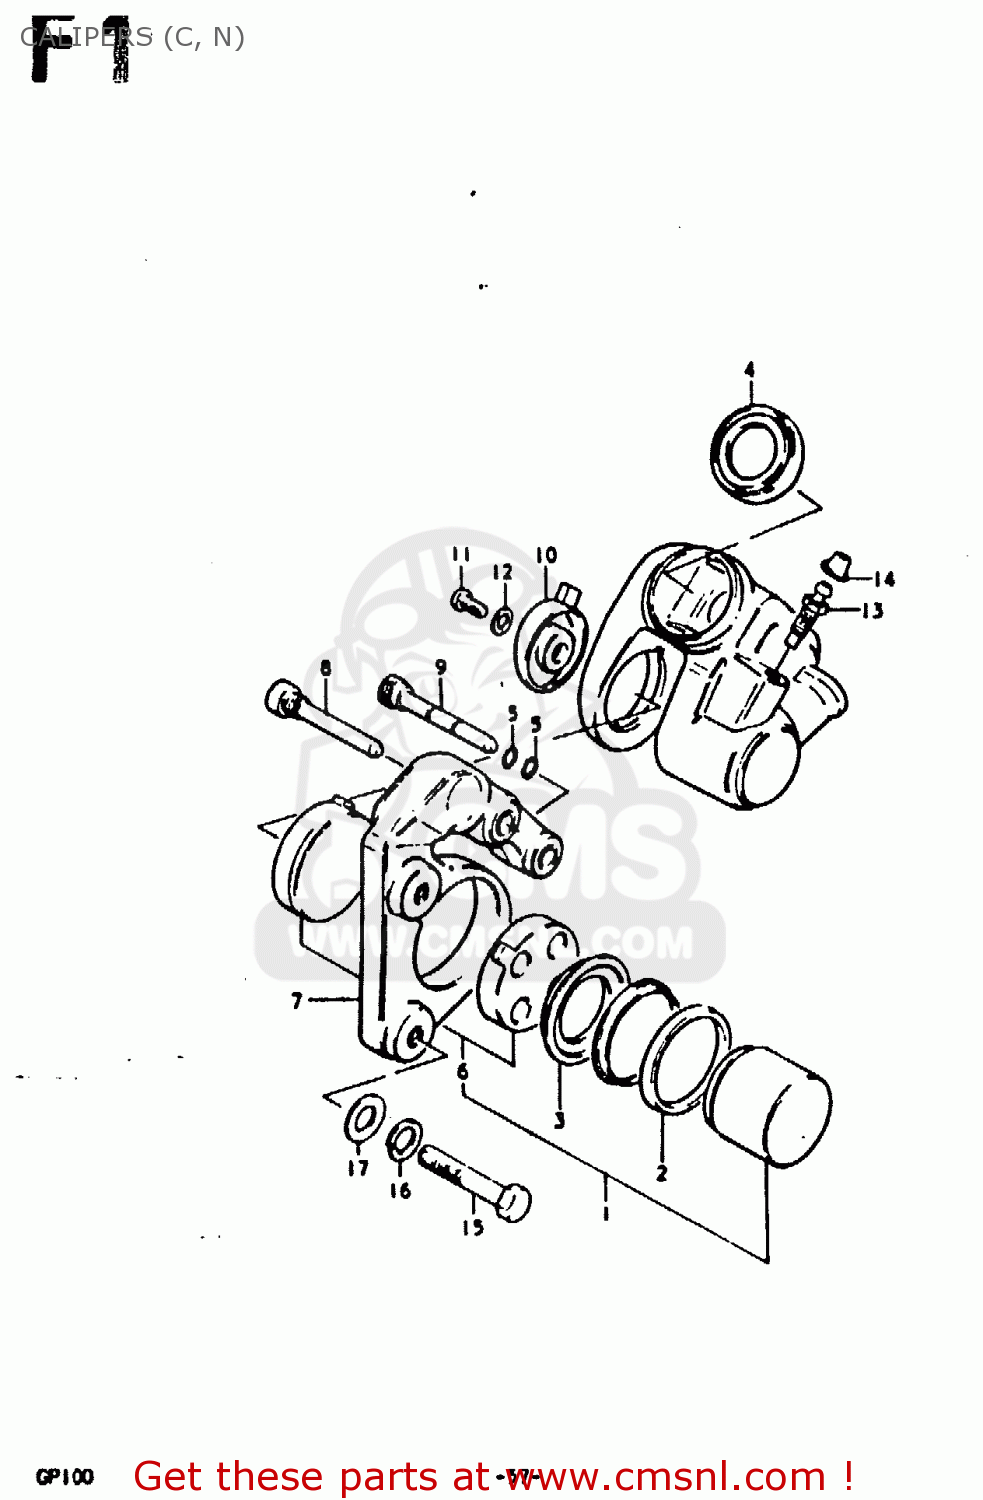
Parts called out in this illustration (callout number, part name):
1	PISTON & PAD SET
2	SEAL, PISTON
3	BOOT, PISTON
4	BOOT, HOLDER
5	O RING, AXLE
6	PAD SET
7	HOLDER, CALIPERS
8	AXLE, CALIPERS NO.1
9	AXLE, CALIPERS NO.2
10	COVER, CYLINDER
11	SCREW
12	WASHER
13	BLEEDER
14	CAP,BLEEDER PL
15	BOLT
16	WASHER,LOCK,8.
17	WASHER
